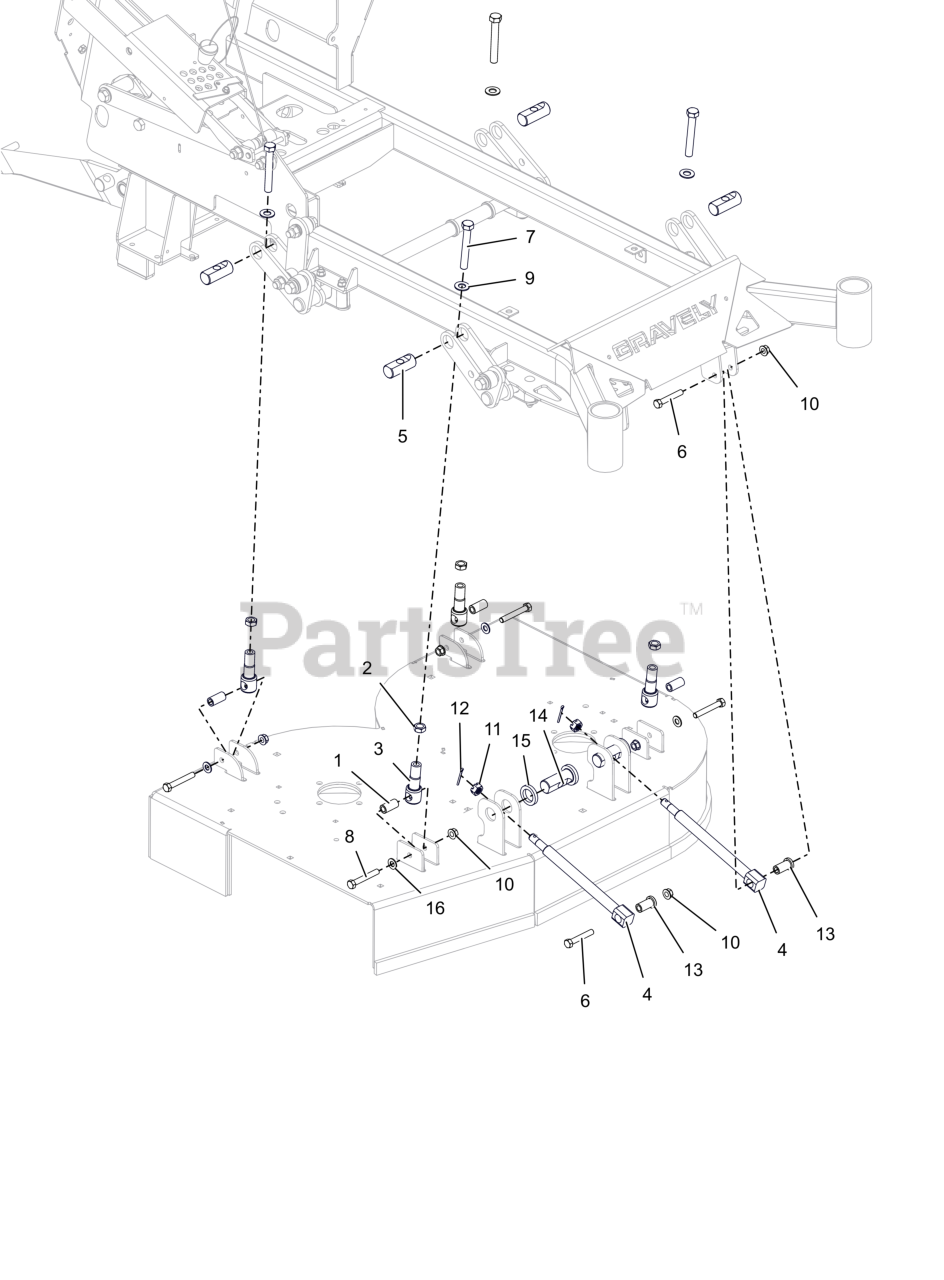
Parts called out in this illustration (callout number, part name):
1	SPACER, DECK LEVELING
2	NUT-JAM .500-13 G2 ZCC
3	LINK, DECK LIFT FORMED
4	DRAG,LINK-HD
5	PIN, DECK LIFT
6	BLT,HEX .38-16X2.25 G5 ZCC
7	BLT, HEX 0.5-13X3.5F GR5 ZCC
8	BLT, HEX .38-16X2.50 G8 ZCC
9	WSHR, FLT .557X1.040X.102 ZCC
10	NUT-LK-CTR-FLG .375-16 GF ZCC
11	NUT-SL .50-13
12	PIN,CTR.12X1.25EXTPRSQCT ZC120
13	SPCR, DRAG LINK
14	PIN, DECK LIFT
15	WSHR-FL-STL 1.0X1.50X.25
16	WSHR,FLT .406X.812X.065 ZCC
